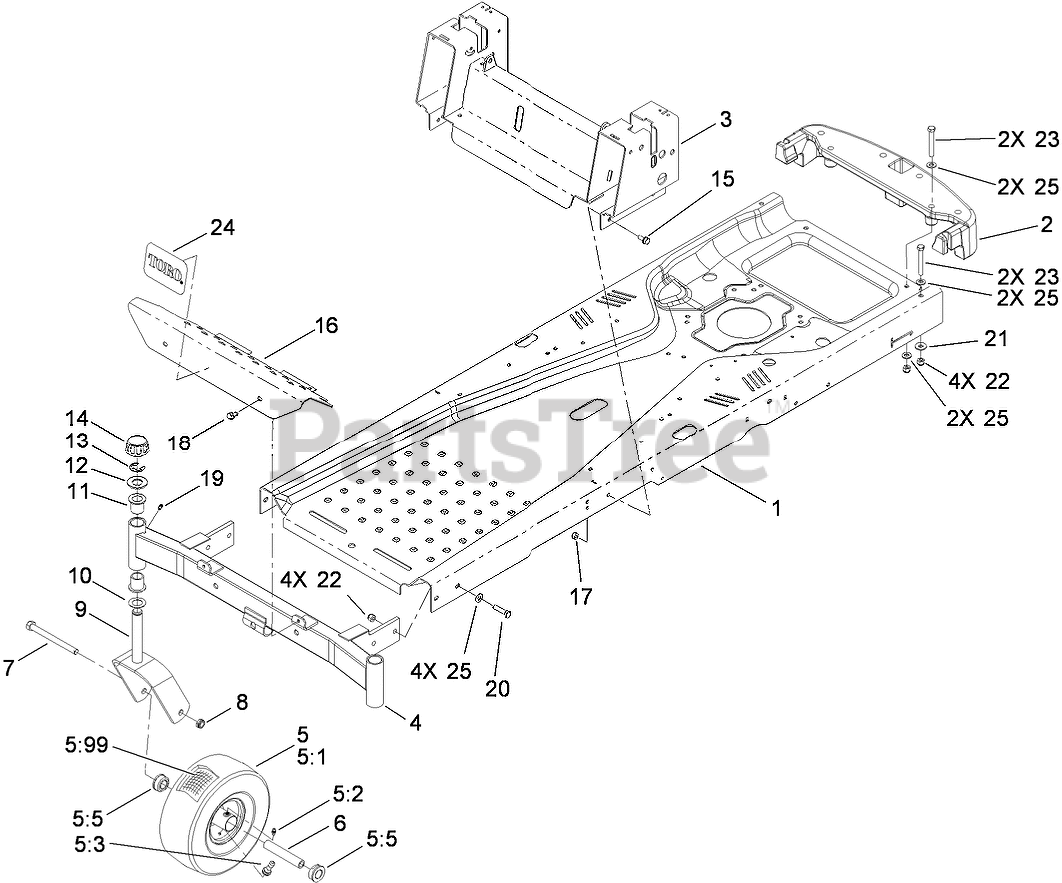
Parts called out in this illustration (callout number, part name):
2	BUMPER-REAR
3	SEAT PIVOT/CONTROL ASM
4	FRONT AXLE ASM
5	FRONT WHEEL AND TIRE ASM
5:2	FITTING-GREASE
5:3	STEM-VALVE
5:5	BUSHING-FLANGE
5:99	TUBE-INNER (W/VALVE)
6	BUSHING-SPANNER
7	SCREW-HH
8	NUT-LOCK, NI
9	CASTER FORK ASM
10	WASHER-THRUST
11	BEARING-FLANGED
12	WASHER
13	RING-RETAINING, EXT
14	CAP-HUB
15	SCREW-HHF
16	FOOTREST
17	NUT-LOCK, NI
18	SCREW-HWH
19	FITTING-GREASE
20	SCREW-HH
21	WASHER-HARDENED
22	NUT-LOCK, NI
23	SCREW-HH
24	DECAL
25	WASHER-FLAT
